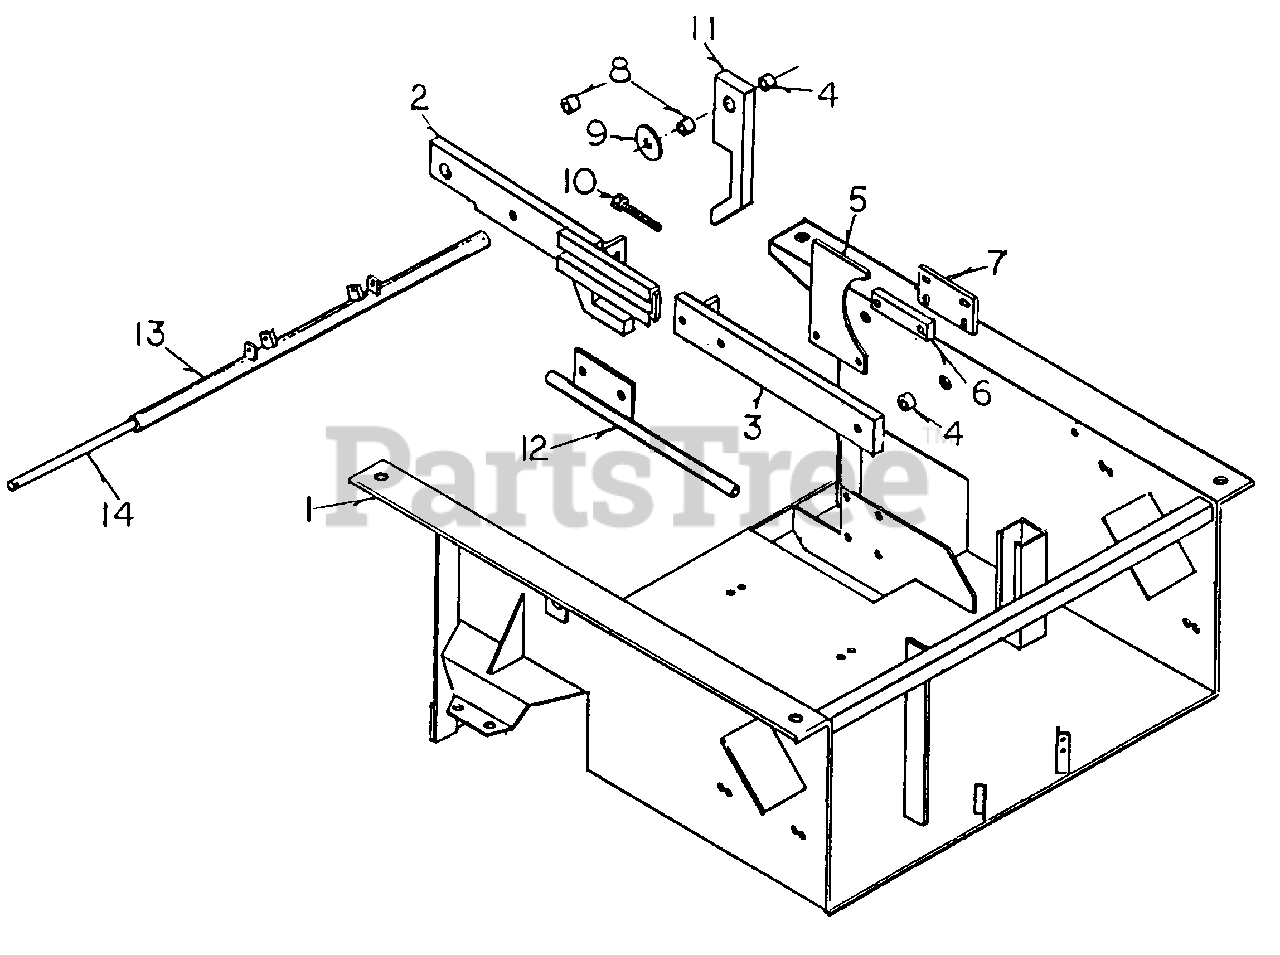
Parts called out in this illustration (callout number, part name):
1	Base
2	RH Deck Lift Arm, Front RH
3	Deck Lift Arm, Back
4	Bushing, Short
5	Belt Retainer
6	Belt Retainer Spacer
7	Belt Retainer Mount
8	Bushing, Long
10	Deck Belt Adjustment Bolt
11	Forward Nose Down Lock
14	Cross Bar Pin
